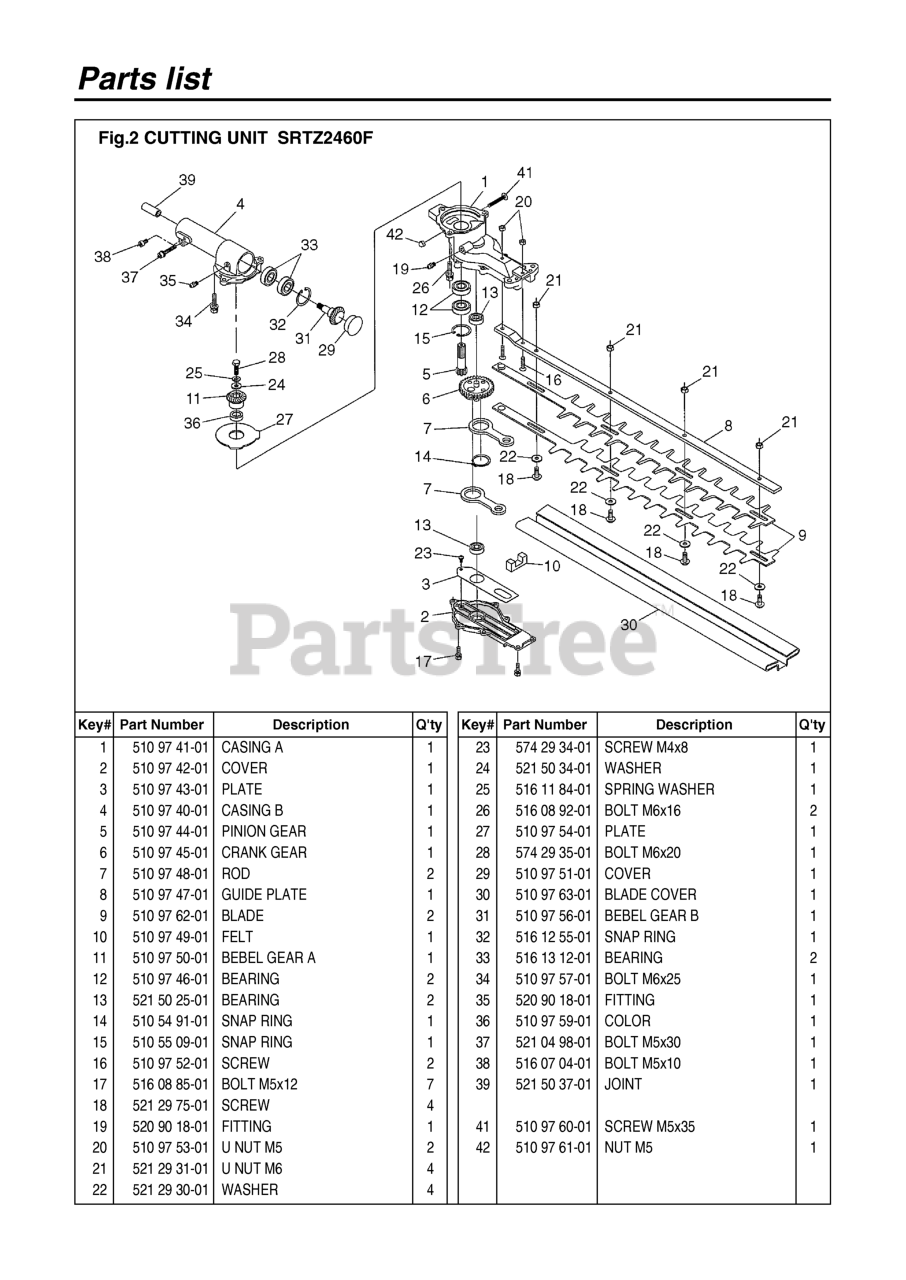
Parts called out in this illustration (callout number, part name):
1	CASING (REPLS -6
4	CASING (REPLS -6
5	PINION GEAR
6	CRANK GEAR
8	GUIDE PLATE
11	BEVEL GEAR A
13	BEARING
14	SNAP RING
15	SNAP RING
17	BOLT, M5 x 25
18	SCREW(R3873,3884
19	FITTING, GREASE
20	U NUT M5
21	NUT, M6
22	WASHER RPL 38731
24	WASHER,6x15x2.0(
25	WASHER, M6 x 15
26	BOLT, M6 x 16
30	BLADE COVER
31	BEVEL GEAR B
32	RING,SNAP M26x1.
34	BOLT M6X25
35	FITTING, GREASE
37	BOLT
38	BOLT, M5 x 12
39	JOINT (RPLS T307
41	SCREW M5X35
